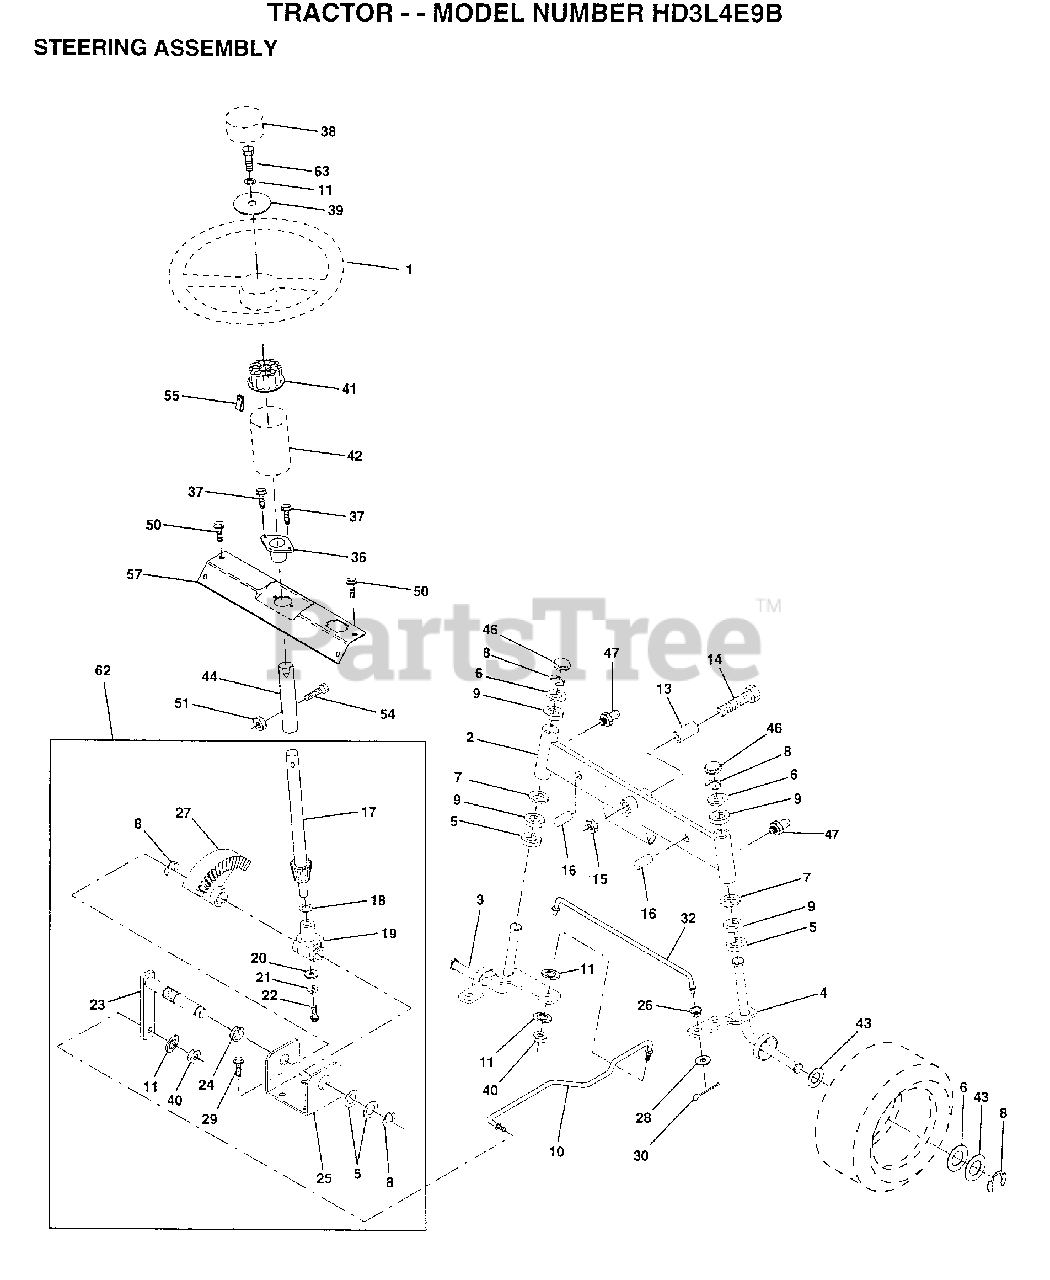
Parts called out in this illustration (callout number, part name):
1	WHEEL STR AYP BLK
2	AXLE ASM FRONT
3	SPINDLE LH
4	SPINDLE RH
5	WASHER .T
6	WASHER
7	WASHER
8	RING
9	COL. SRTG. BEAR.
11	LOCKWASHER
13	BEARING
14	BOLT HEX 5/8-11
15	"NUT-LOC,FLANGE LT"
16	AXLE PIN
17	SHAFT ASM STEERIN
18	THRUST WASHER
19	SUPPORT.SHAFT
21	LOCKWASHER
22	SCREW.SCKTHD.CAP
24	NYLINER T
25	"BRKT,STEERING"
26	BUSHING.DRAGLINK
27	GEAR SECTOR
28	WASHER
29	SCREW
30	COTTER PIN
32	TIE ROD
37	"SCREW-TT,10-32 FL"
38	CAP STEER AYP
39	WASHER T
40	GRIPCO NUT
41	ADAPTER LT
42	BOOT SHAFT STEER
43	WASHER
44	SHAFT EXT STEERIN
46	CAP
47	ZERK M
50	SCREW HEX CRT
51	NUT
54	BOLT
55	CLIP TINNERMAN
57	SUPPORT SHAFT STR
63	BOLT
